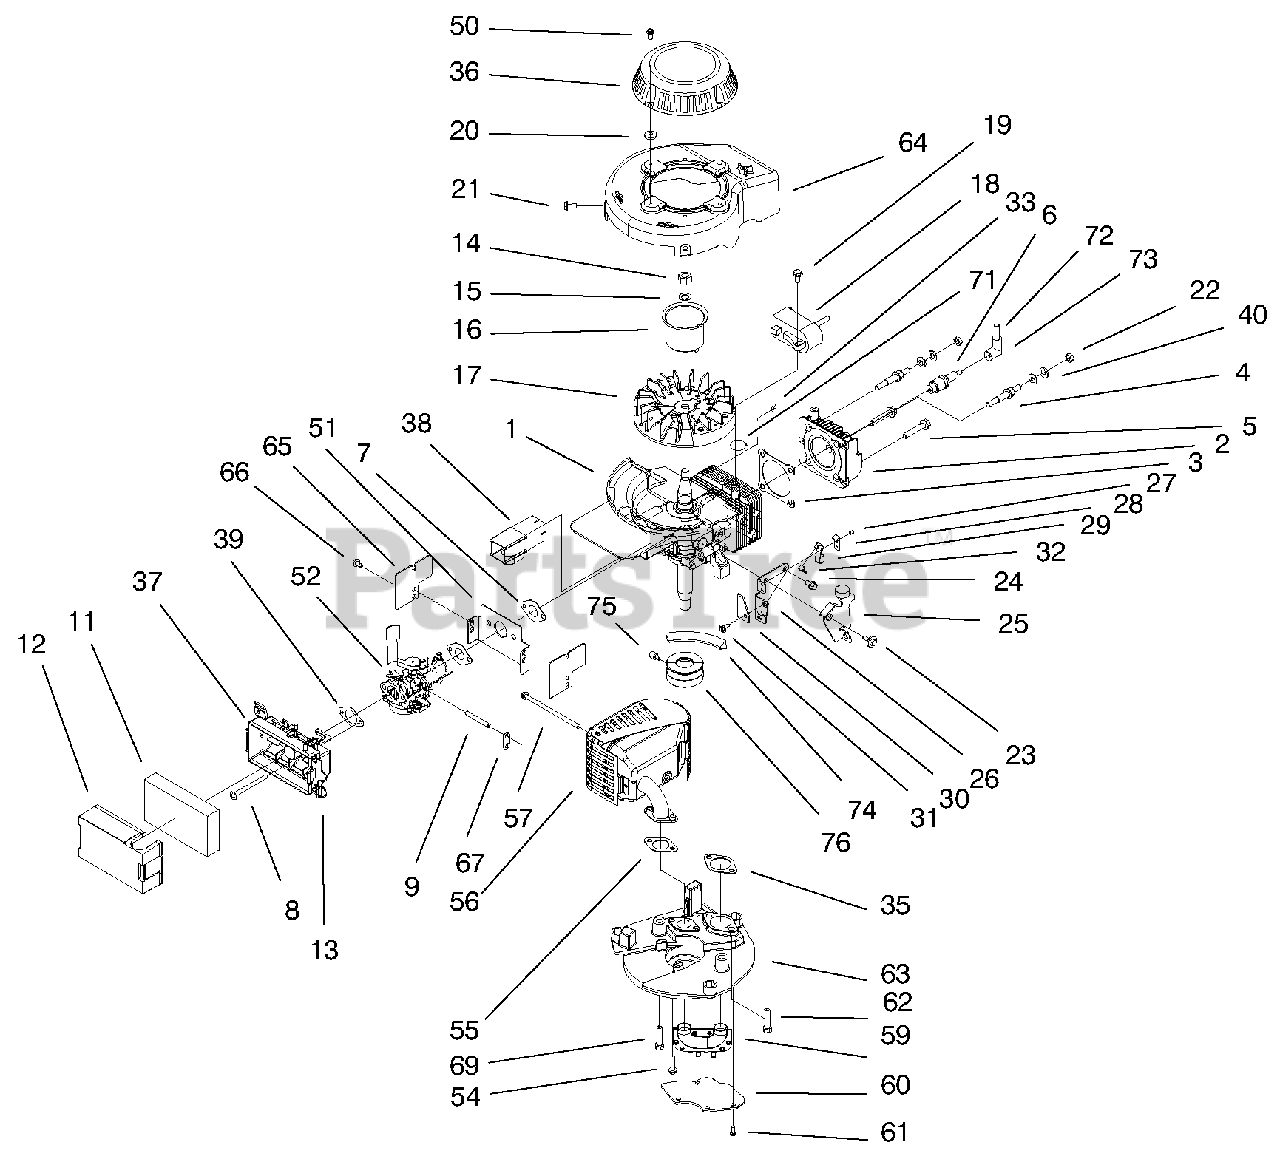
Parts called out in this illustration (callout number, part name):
1	Short Block ASM
3	Gasket-Head
6	Spark Plug
7	Intake Gasket
9	Primer Hose
11	Element-Air Filter
12	Cover-Air Filter
13	Retainer-Filter
15	Washer-Lock
16	Hub-Starter
17	Flywheel Machined Recoil
18	Ignition ASM
19	Screw-HWH
21	Screw
22	Nut-Lock
23	Shoulder Screw Brake
24	Screw (Brake)
25	ASM-Brake Plate
26	Plate-Mount Brake
27	Rivet-Self Expand Plas
28	Strap-Insulation
29	Strap-Ground
30	Stop-Ground Strap
31	Screw-Thread Forming
32	Brake Switch Lead Wire
35	Gasket-Exhaust
36	ASM-Starter
37	Air Filter Base ASM
39	Gasket-Filter Base
40	Washer-Lock
50	Screw-Sems
51	Heat Shield
52	Carburetor ASM
54	Screw-HWH
56	Muffler & Guard
59	Transfer Tube
60	Cover Plate
62	Screw-HH
63	Muffler Plate Machining
64	Shroud ASM
65	Shield-Gov Int'l
67	Retainer Hose
69	Screw-Hhd Washer
71	Tie Strap
72	Lead & Cover ASM
73	Cover & Terminal
75	Set Screw
